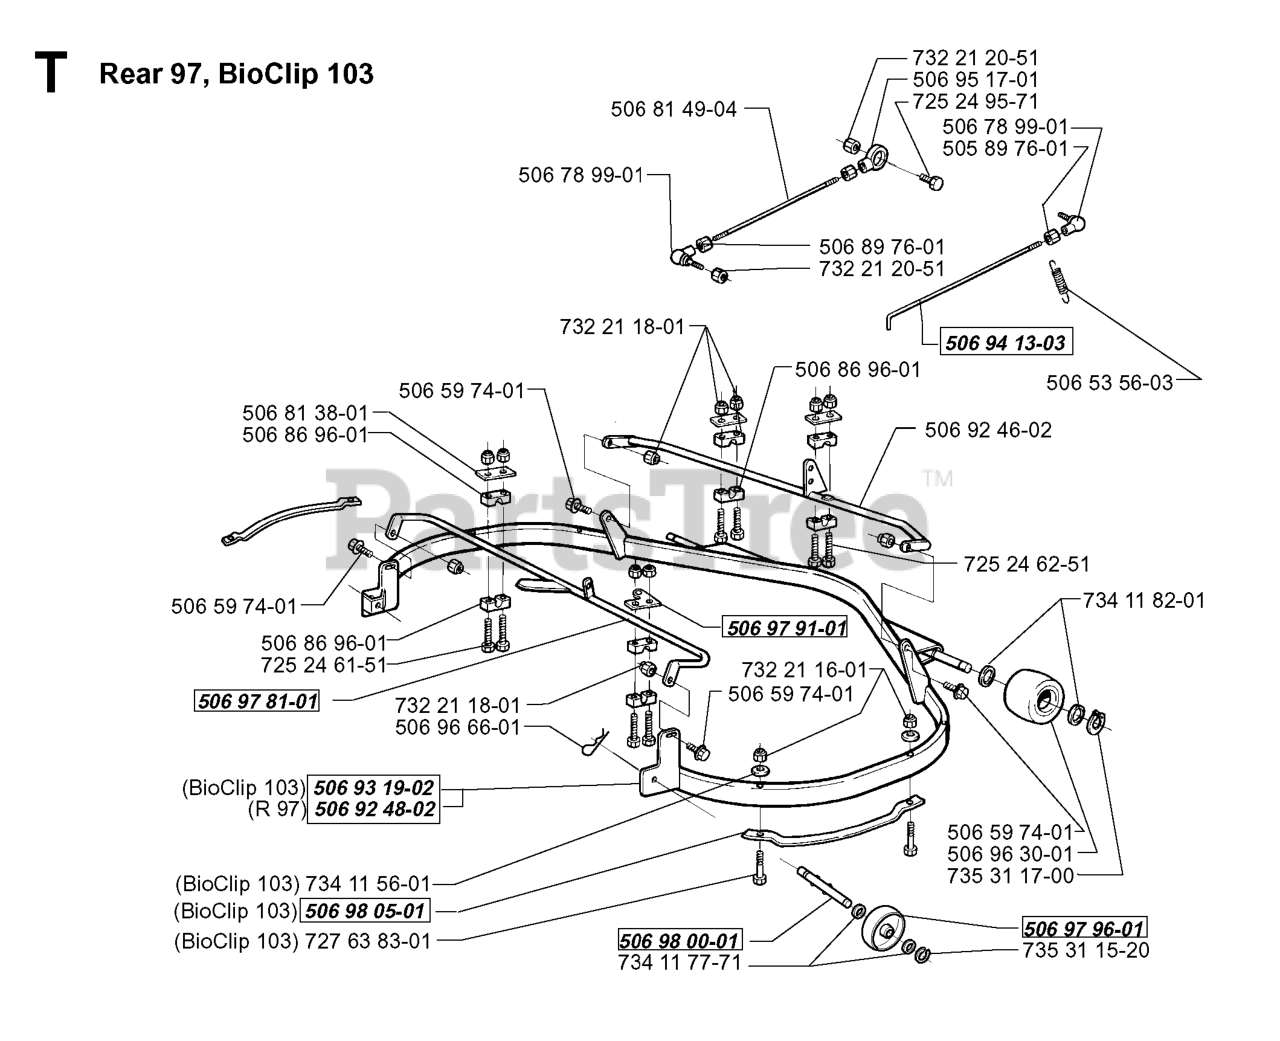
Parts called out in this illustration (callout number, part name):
1	SHAFT, PUMP
2	RETAINIANG RING
3	BALL BEARING 2003043
5	SEAL LIP
6	RETAINING PIN
8	CRADLE BEARING
13	TRUNION ARM
14	GUIDE 2000015 HYD
15	HOUSING KIT, TRANSMISSION
17	BALL BEARING
19	CENTER SECTION KIT
21	LIP SEAL 9008000-0127
22	SHAFT MOTOR 2003034
25	SWASHPLATE,VARIAB
32	BLOCK, CYL ASSY
38	GASKET 2003060
42	CHECK VALVE KIT 2510050
43	CHECK VALVE KIT 2510050
44	CHARGE RELIEF KIT 2510011
53	KIT,BYPASS VALVE(2513011)
60	SPRING 2003014
62	O-RING.HYDRO GEAR.9004101-1340
63	CHARGE PUMP KIT
64	GEROTOR ASSEMBLY
67	SCREW, SOCKET HEAD CAP
